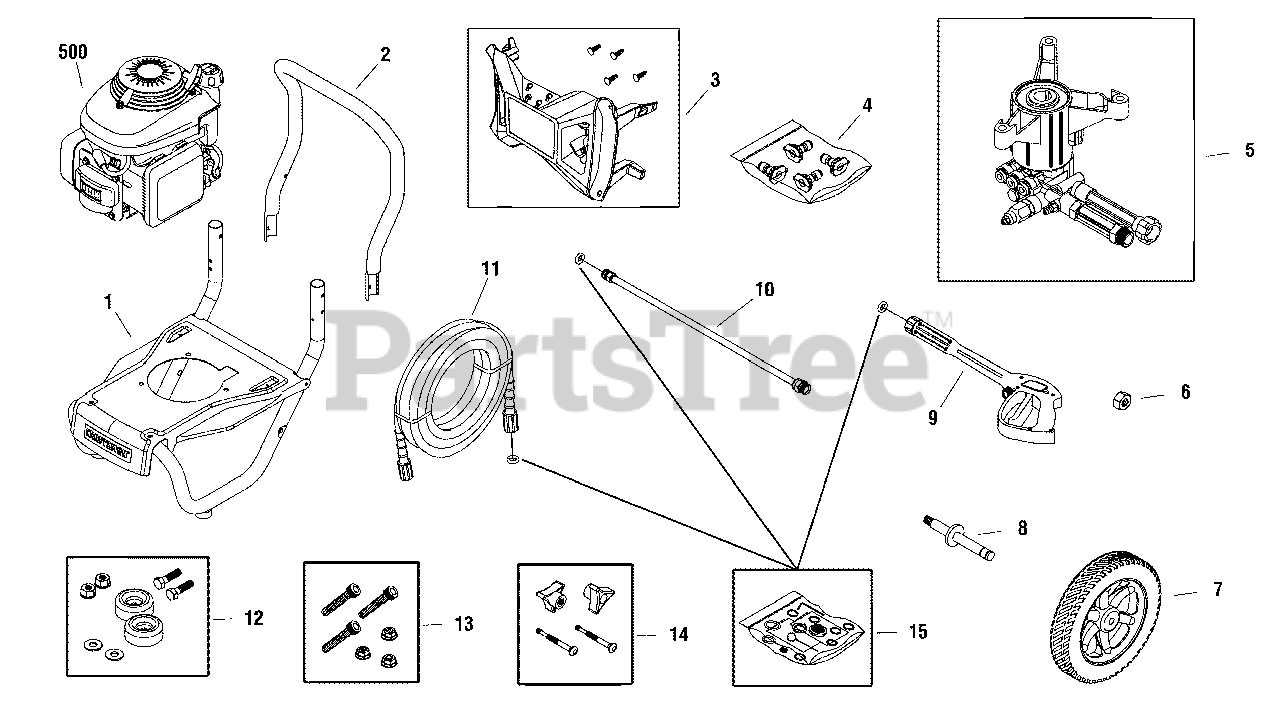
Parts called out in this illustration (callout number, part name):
5	PUMP
6	NUT
9	GUN
10	EXTENSION, QC
11	HOSE
12	MOUNT, Vibration
13	KIT, Hardware Pump Mounting
15	KIT, O-Ring
500	*ENGINE
